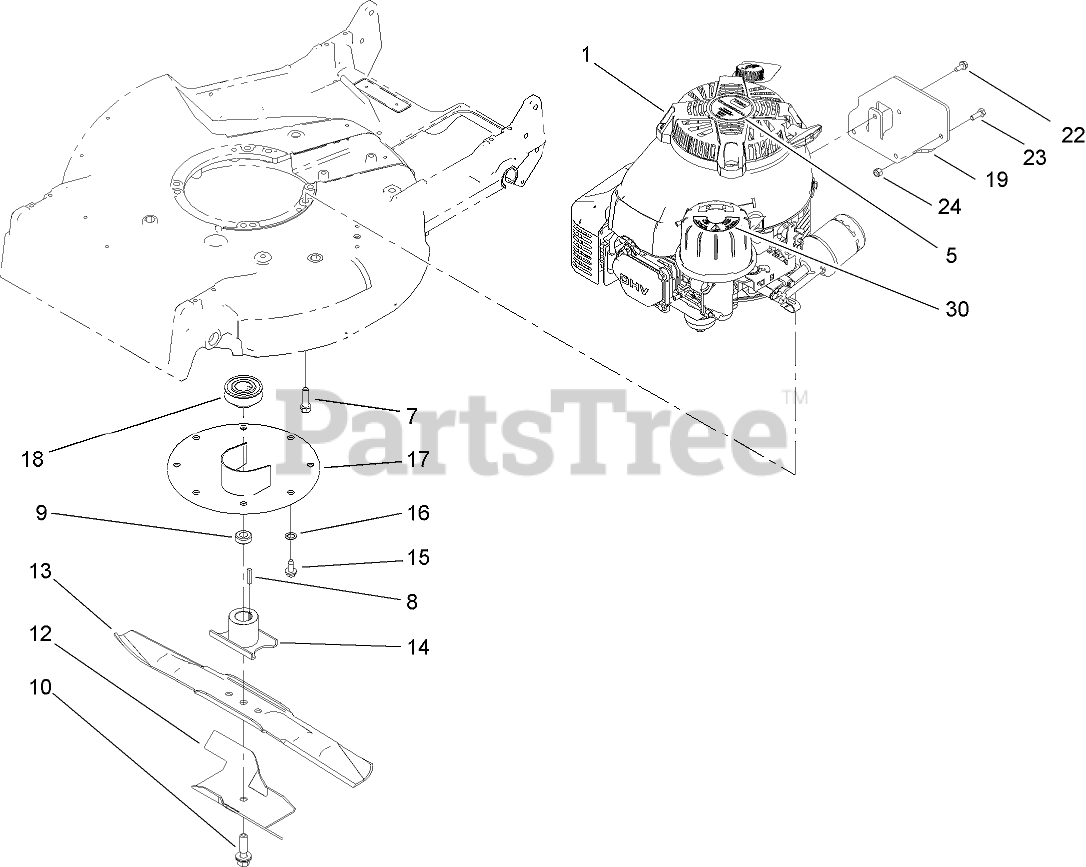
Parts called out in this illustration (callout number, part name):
1	ENGINE-Kawasaki, FJ180V-AS39
5	DECAL
7	SCREW-TAPTITE
8	KEY-SQUARE
9	Spacer-Retainer, Blade
10	BOLT-BLADE
12	STIFFENER-BLADE
13	BLADE-21 INCH
14	RETAINER-BLADE
15	SCREW-HWHTF
16	WASHER-LOCK, INTERNAL
17	PROTECTOR-CRANKSHAFT
18	PULLEY-DRIVER
19	BRACKET-ADAPTER, TANK
22	SCREW-HWH
23	SCREW-HH
24	NUT-LOCK, NI
